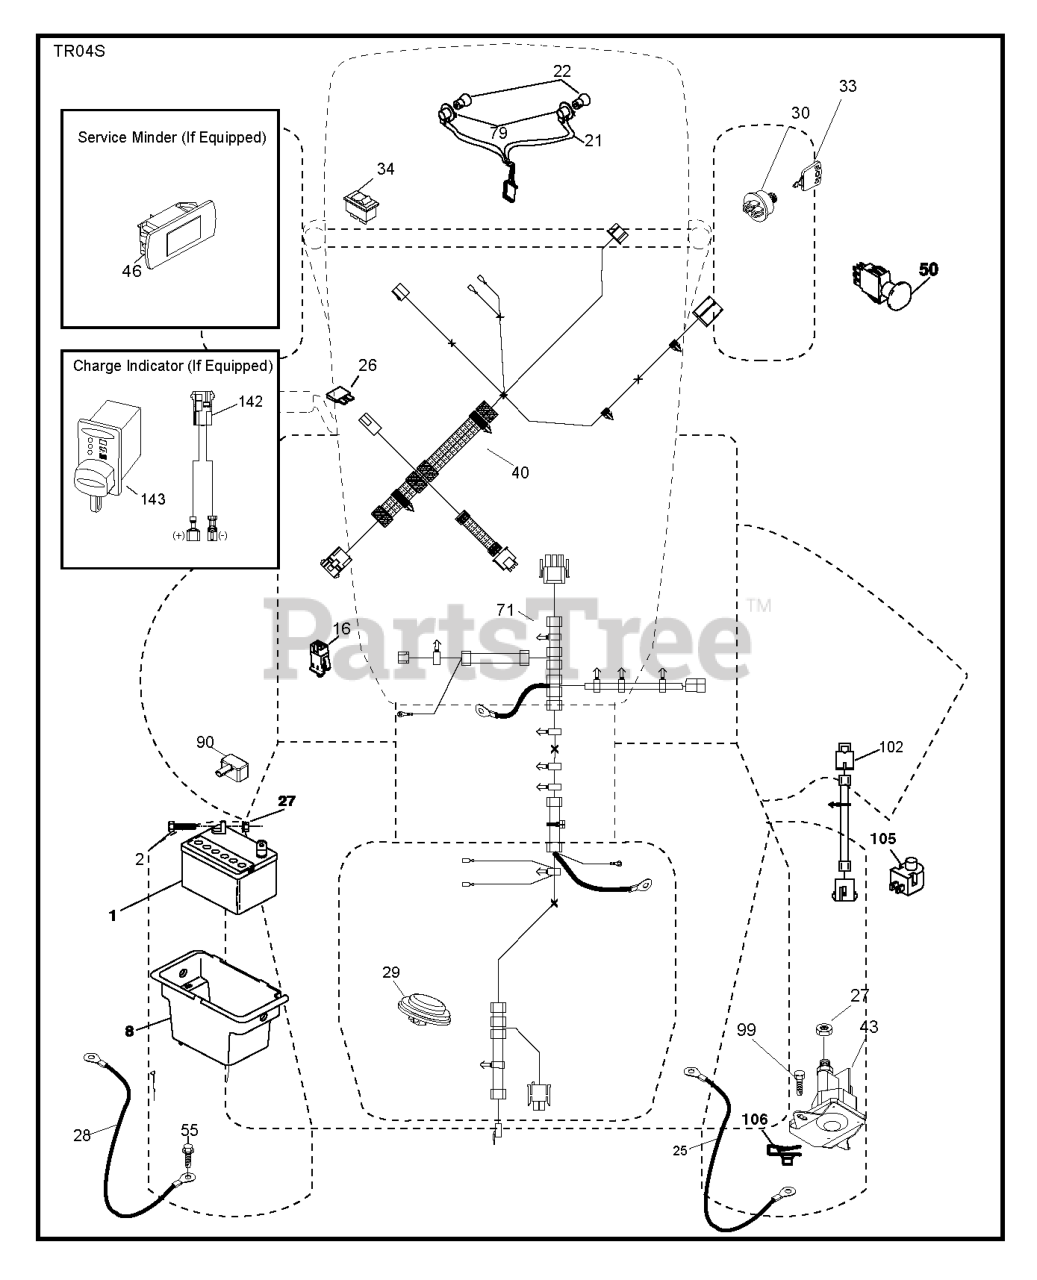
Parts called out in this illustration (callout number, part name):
1	Battery 12 Volt 25 Amp
2	BOLT.HEX.1/4.X.3/4.DICHROMATE
8	BOX.BATTERY.MNT.REAR.L
16	SWITCH INTERLOOK PUSH-IN
21	HARNESS.LIGHT W/4152J BULBS
25	CABLE.BATT.RED.8GA.17
26	FUSE 20AMP
27	NUT
28	CABLE.GROUND.REAR.BATTERY.8G
29	SWITCH.SEAT.DELTA.OPC.
30	SWITCH.IGN.DELTA.W.LGH.ROS
33	KEY.CHAIN.BLISTER.PACK.GEN.INT
40	HARNESS.TEX.DASH.ELEC.REAR BAT
43	SOLENOID.W/BRASS.PLUNGER
46	RP.GUAGE.SRVCMNDR.HRMTR.
50	RP.PTO.SWITCH.8 TERMINAL.BLACK
55	SCREW 5/16"
71	HARNESS.TEX.CHSSIS.REAR.BATT
79	BULB HOLDER ASM.
90	COVER.TERMINAL.BATTERY
99	SCREW HEXWSHR 1/4-20X3/4
102	HARNESS PIGTAIL PCH TEX ROS
105	REVERSE SWITCH
106	1/4-20 U NUT
